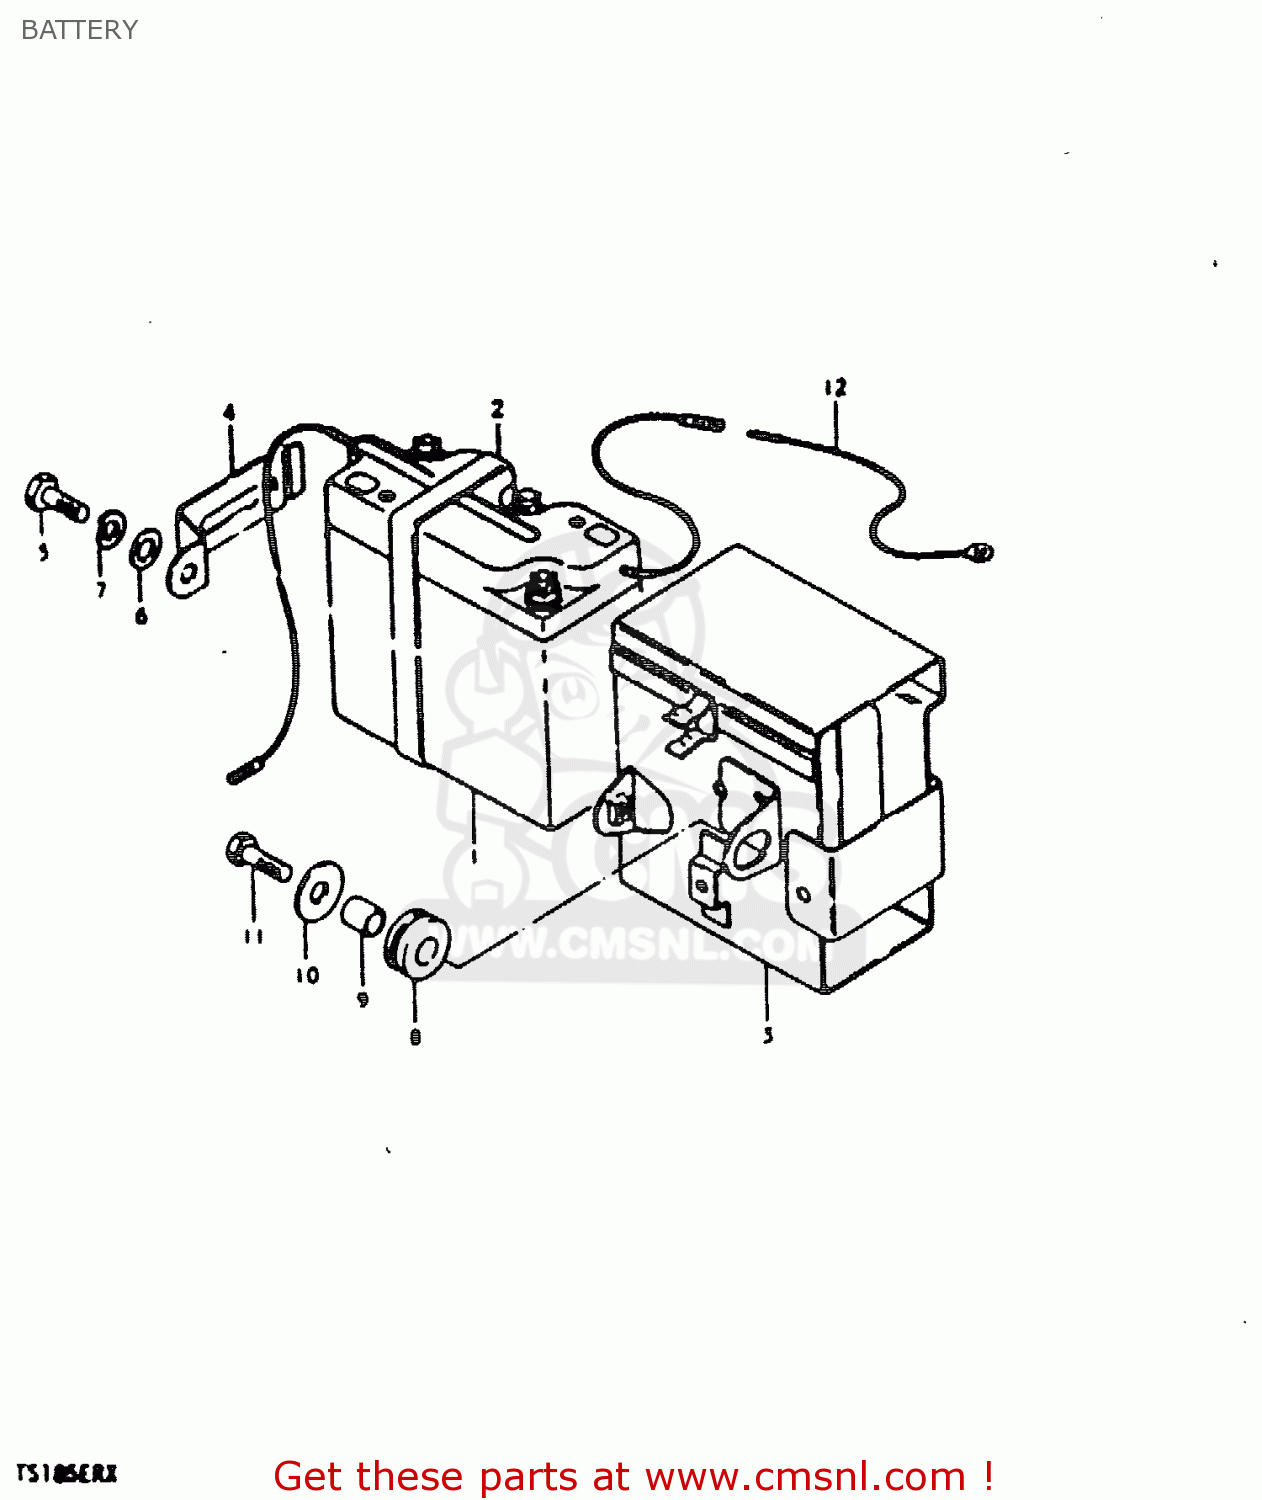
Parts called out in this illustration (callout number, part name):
1	BATTERY(6N4B-2A,6V4.2AH)
2	PROTECTOR,BATTERY
3	HOLDER,BATTERY
4	PLATE,BATTERY HOLDER
5	SCREW(6X10)
6	WASHER
7	LOCK WASHER
8	CUSHION
9	SPACER (7X9X7)
10	WASHER (6.5X20X1.2)
11	SCREW
12	LEAD WIRE
